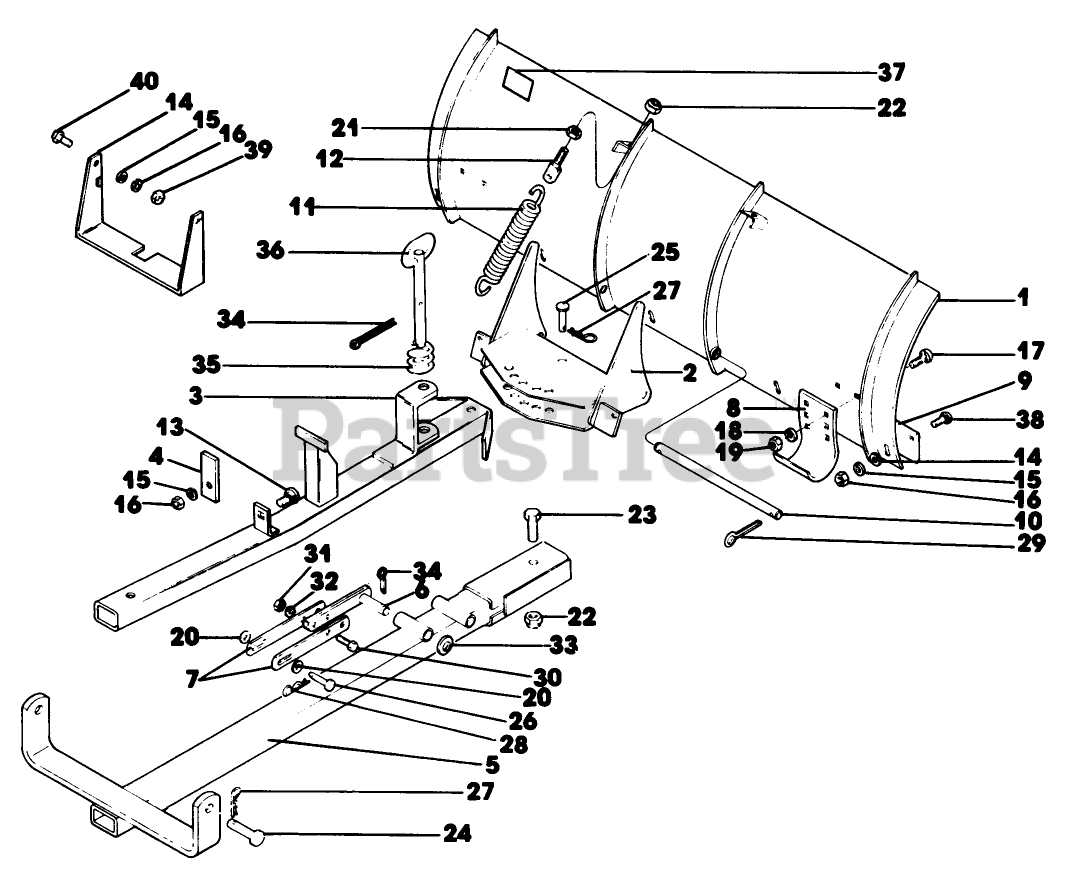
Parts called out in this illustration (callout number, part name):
4	Frame Stop
15	Lock Washer 5/16 Plated
30	Cap Screw, Hex Hd. 7/16-14 x 1-1/2 Plated, Grade 5
